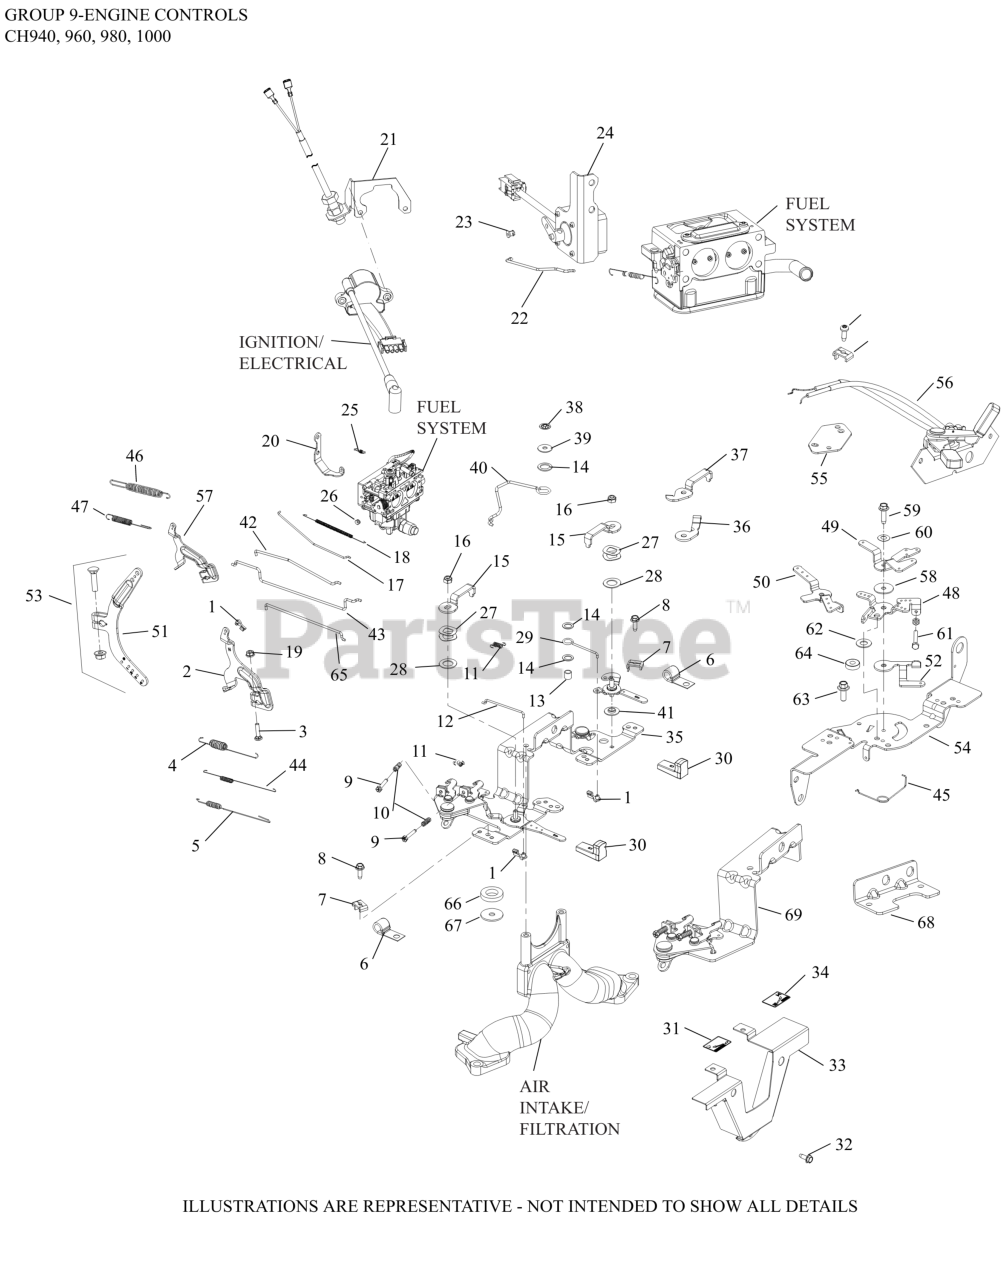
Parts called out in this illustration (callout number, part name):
1	BUSHING, THROTTLE LINKAGE
3	BOLT, RD HD SQ NECK M6X1.0X25
4	SPRING, GOVERNOR IDLE
5	SPRING, GOVERNOR, HIGH SPEED
7	CLAMP, CABLE-(#2523753S)
8	SCREW, THREAD FORMING
9	SCREW, PHL THD FRM M4X0.7X25
11	SPRING, RETURN
12	LINKAGE, THROTTLE LEVER
14	WASHER, NYLON
17	LINKAGE, THROTTLE
18	SPRING, LINKAGE
19	NUT, FLG M6X1.0
20	BRACKET, CHOKE ASSIST
23	BUSHING, LINKAGE RETAINING
25	SPRING, CHOKE ASSIST
26	BUSHING-USE 25 158 08-S
29	LINKAGE, CONTROL
35	CONTROL ASSEMBLY, SPEED (HORIZONTAL)
38	RETAINER, PALNUT
39	WASHER, STEEL
40	LINKAGE, CHOKE HORIZONTAL
41	WASHER, NYLON SHOULDER
57	KIT, GOVERNOR LEVER
62	WASHER, FLAT 9 MM
